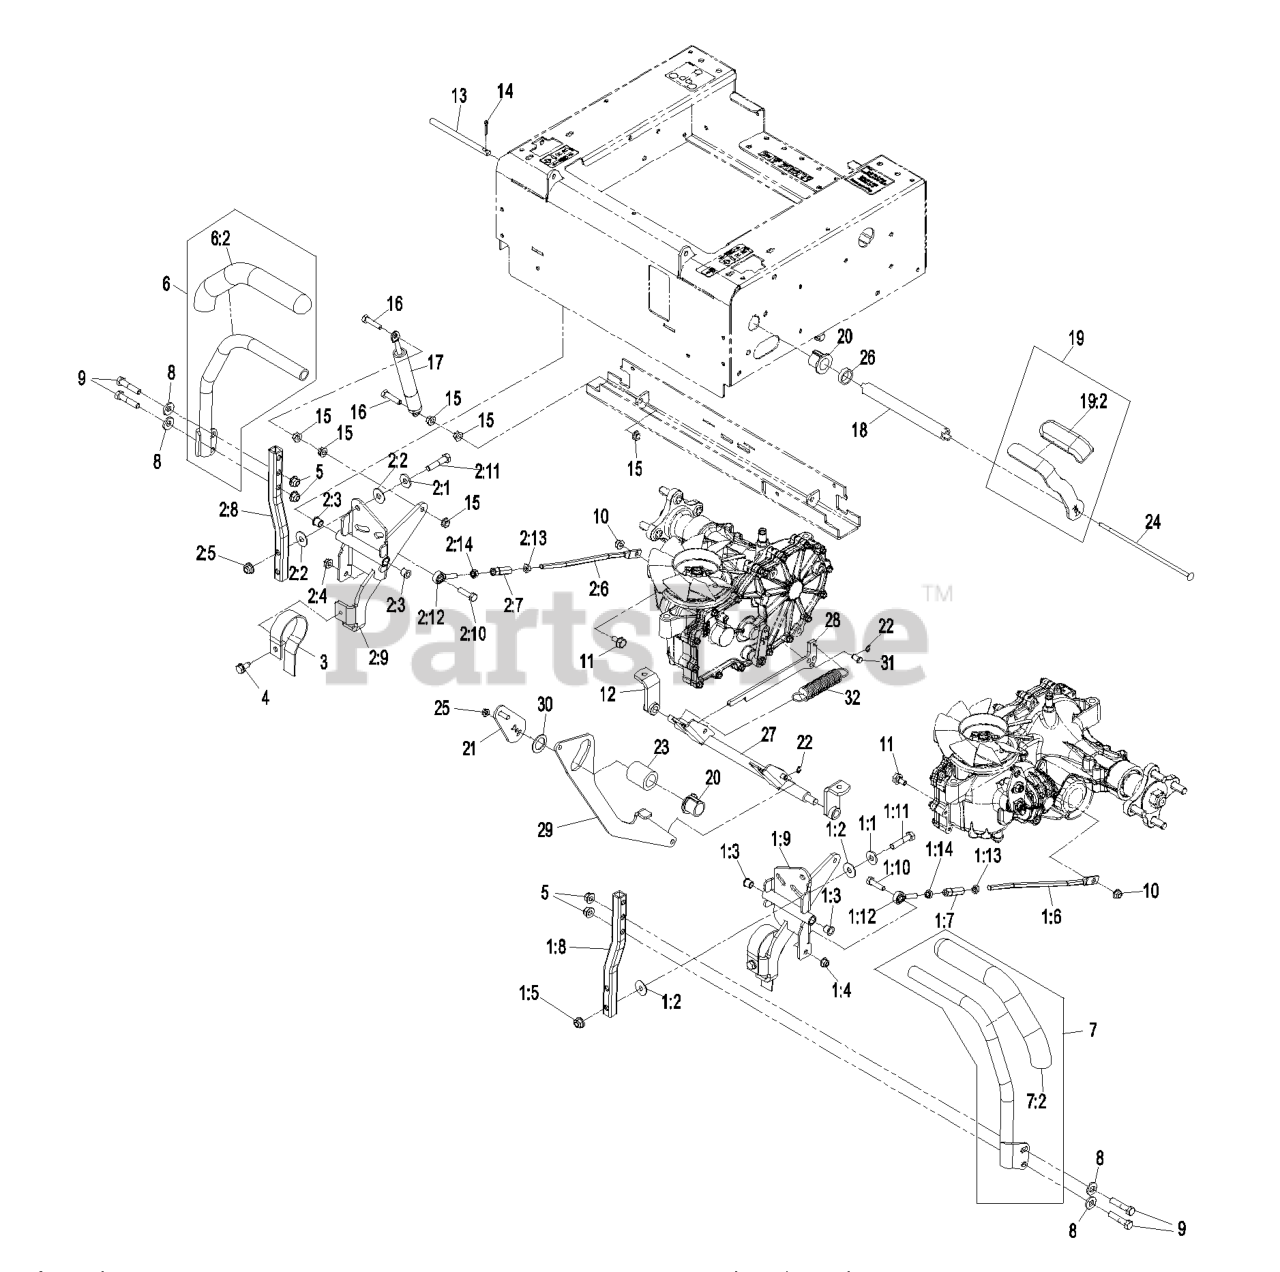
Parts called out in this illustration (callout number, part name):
1	Asm, Motion Control Lh
1:1	WASHER
1:2	WASHER-PLASTIC
1:3	BEARING
1:4	NUT-HF, NI
1:5	NUT-HF, NI
1:6	ROD-STEERING
1:7	NUT-ROD ADJUSTMENT
1:10	SCREW-HH
1:11	SCREW-HH
1:12	BEARING-ROD END, LH
1:13	NUT-JAM
1:14	NUT-JAM
2	Asm, Motion Control Rh
2:1	WASHER
2:2	WASHER-PLASTIC
2:3	BEARING
2:4	NUT-HF, NI
2:5	NUT-HF, NI
2:6	ROD-STEERING
2:7	NUT-ROD ADJUSTMENT
2:10	SCREW-HH
2:11	SCREW-HH
2:12	BEARING-ROD END, LH
2:13	NUT-JAM
2:14	NUT-JAM
3	SPRING-LEAF
4	Screw-HWH 5/16-18 X 3/4 Tf
5	NUT-HF, NI
6	RH CONTROL HANDLE ASM
7	LH CONTROL HANDLE ASM
8	WASHER-BELLEVILLE
9	SCREW-HH
10	NUT-HF, NI
11	BOLT-SHOULDER,HFH
12	BRAKE PIVOT ASM
13	PIN-CONTROL PIVOT
14	PIN-COTTER
16	SCREW-HH
17	DAMPER-MOTION CONTROL
18	TUBE-BRAKE PIVOT
19	LEVER ASM
19:2	GRIP-LEVER
20	BUSHING-FLANGE, KEYED
21	WLD,BELLCRANK
22	E-RING
24	BOLT-CARR
27	BRAKE SHAFT ASM
28	LINK-BRAKE ACTUATION
29	ARM-BRAKE
31	PIN-CLEVIS
32	SPRING-EXTENSION
